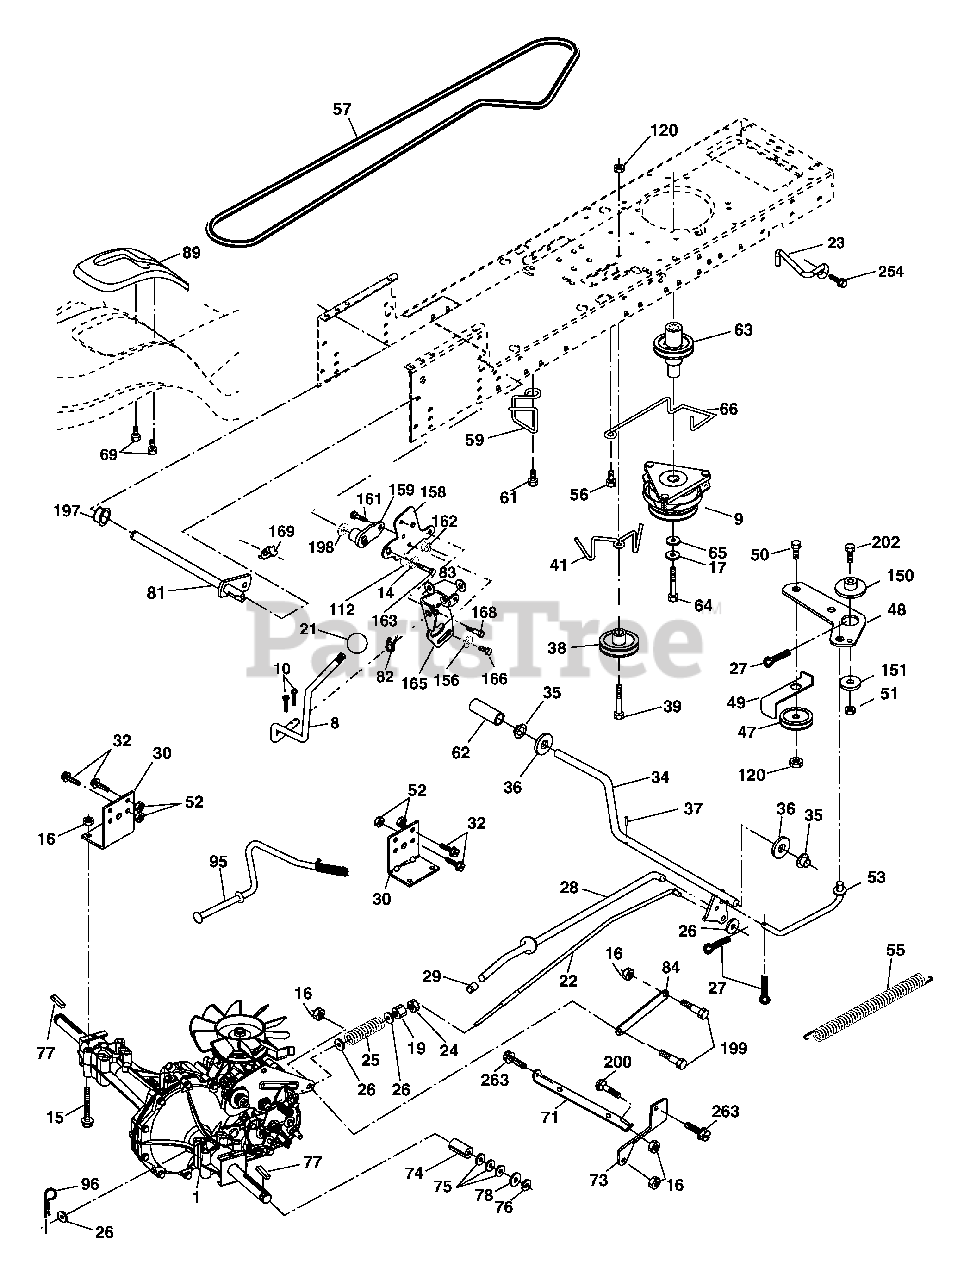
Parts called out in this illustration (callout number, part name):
1	Transaxle
8	Rod Shift
9	Clutch Electric
10	Pin Cotter 1/8 x 1 CAD
14	Washer Lock Hvy. Helical
15	Bolt, Hex FLGHD 5/16-18 Gr. 5
16	Nut Lock Hex W/Ins 5/16-18 unc P
17	Washer 1-1/2 OD x 15/32 ID x 2.50
19	Nut Lock Hex W/Wsh 3/8-16 unc
21	knob 1/2-13
22	Rod, Brake Hydro
23	Bracket Anti-Rotation
24	Nut Hex Jam 3/8-16
25	Spring, Brake Rod
26	Washer
27	Pin Cotter 1/8 x 3/4 CAD.
28	Rod, Parking Brake
29	Cap, Parking Brake
30	Bracket, Transaxle
32	Bolt Hex Hd 5/16-18 unc x 3/4
34	Shaft, Foot Pedal Nibbed
35	Bearing, Nylon
36	Washer 21/32 x 1 x 16 Ga.
37	Pin, Roll 3/16 x 1
38	Pulley, Idler, Composite
39	Bolt 3/8-16unc x 2-3/4
41	Keeper, Belt Retainer
47	Pulley, Idler, V-Groove
48	Bellcrank Clutch Grnd Drv STL
49	Retainer, Belt
50	Bolt Carr Sh 3/8-16 x 1-1/2 Gr.5
51	Nut Crownlock 3/8-16 unc
52	Nut Crownlock 5/16-18 unc
53	Link, Clutch
55	Spring, Return, Clutch
56	Screw 3/8-16 x 1.0
57	V-Belt, Ground Drive
59	Keeper, Center Span
61	Screw 3/8-16 x 3/4
62	Cover, Pedal
63	Pulley, Engine
64	Bolt, Hex
65	Washer Lock Hvy Hlcl Spr. 7/16
66	Keeper Belt Engine
69	Screw
71	Strap Torque Lh Hydro
73	Strap Torque Rh Hydro
74	Spacer, Split
75	Washer 25/32 x 1-1/4 x 16 Ga.
76	E-Ring
77	Key, Square
78	Washer 25/32 x 1-5/8 x 16 Ga.
81	Shaft Asm. Cross
82	Spring Torsion
83	Washer 17/32 x 3/4 x 16 Ga.
84	Link, Transaxle
89	Console, Shift
95	Control Asm Bypass Hydro
96	Retainer Spring 1" Zinc/Cad
112	Washer 9/32 x 3/4 x 10 Ga.
120	Nut Lock Flg 3/8-16 unc
150	Spacer Retainer
151	Washer 13/32 x 2 x 10 Ga.
156	Washer Srrted 5/16 ID x 1 x .125
158	Bracket Shift Mount
159	Hub Shift
161	Bolt Rdhd Sqnk 1/4-20 x 3/4 Gr. 5
162	Nut Crownlock 1/4-20 unc
163	Bolt Hex Fin 1/4-20 unc x 1 Gr. 5
165	Bracket Pivot Lever
166	Screw 5/16-18 x 5/8
168	Bolt Shoulder 5/16-18 x .561
169	Plate Fastening LT
197	Nyliner Snap-In 5/8" ID
198	Washer Nyl 7/8" ID x .105"
199	Bolt Shoulder 5/16-18 unc
200	Bolt Rdhd Sqnk 5/16-18 unc x 1
202	Bolt 3/8-16 x 1-3/4 Gr. 5
254	Screw 3/8-16 x 1
263	Screw 3/8-16 x .75
